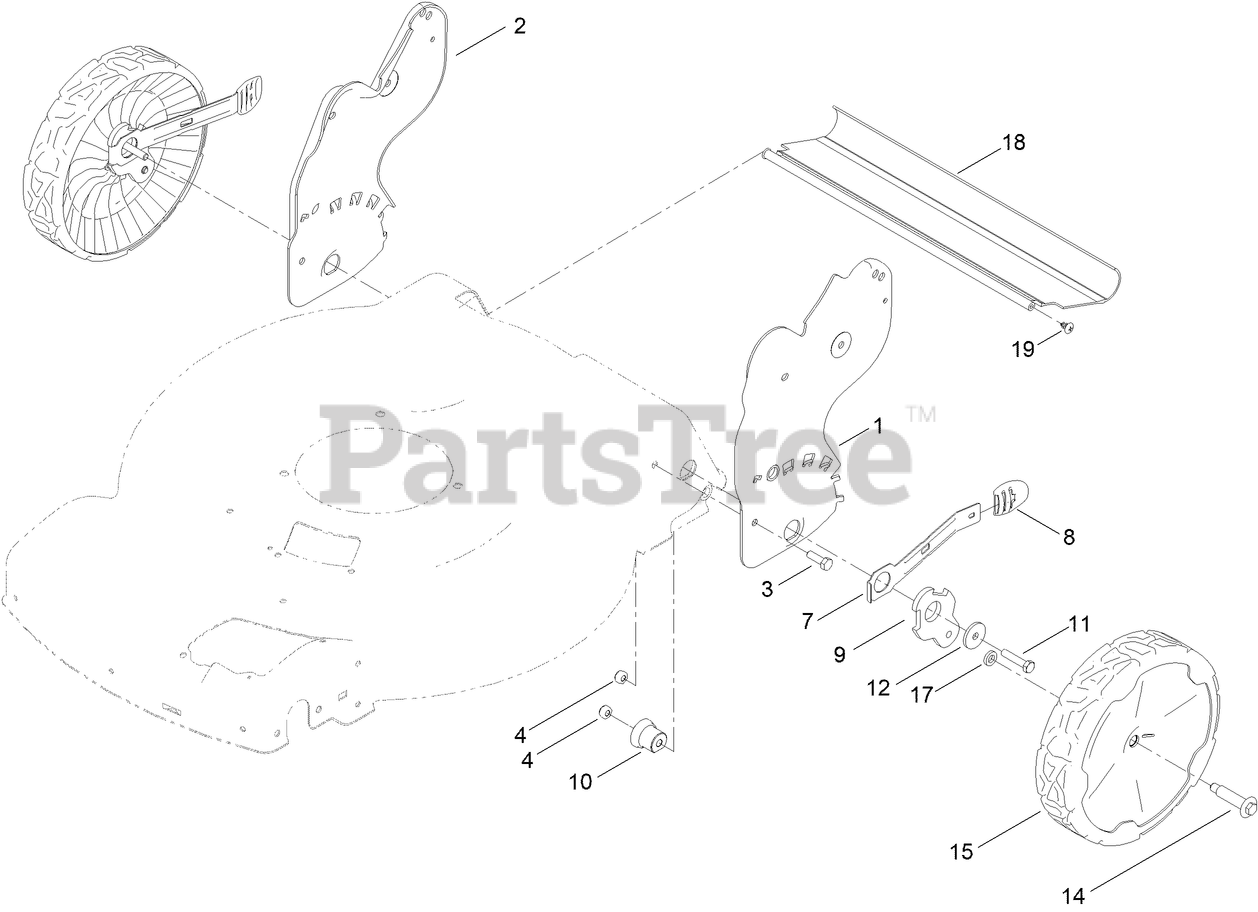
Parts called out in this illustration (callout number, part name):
1	PLATE-HOC, FWD LH
2	PLATE-HOC, FWD RH
3	SCREW-HH
4	NUT-LOCK, NI
7	ARM-SPRING, REAR
8	KNOB-LEVER, HOC
9	ARM-PIVOT, REAR
10	BUSHING-MOUNT, HOC
11	SCREW-HH
12	WASHER-FLAT
14	WHEEL BOLT
15	ASM-9.65" WHEEL, BUSHINGS
17	WASHER-WHEEL BOLT
18	SHIELD-TRAILING
19	SCREW-PTH
